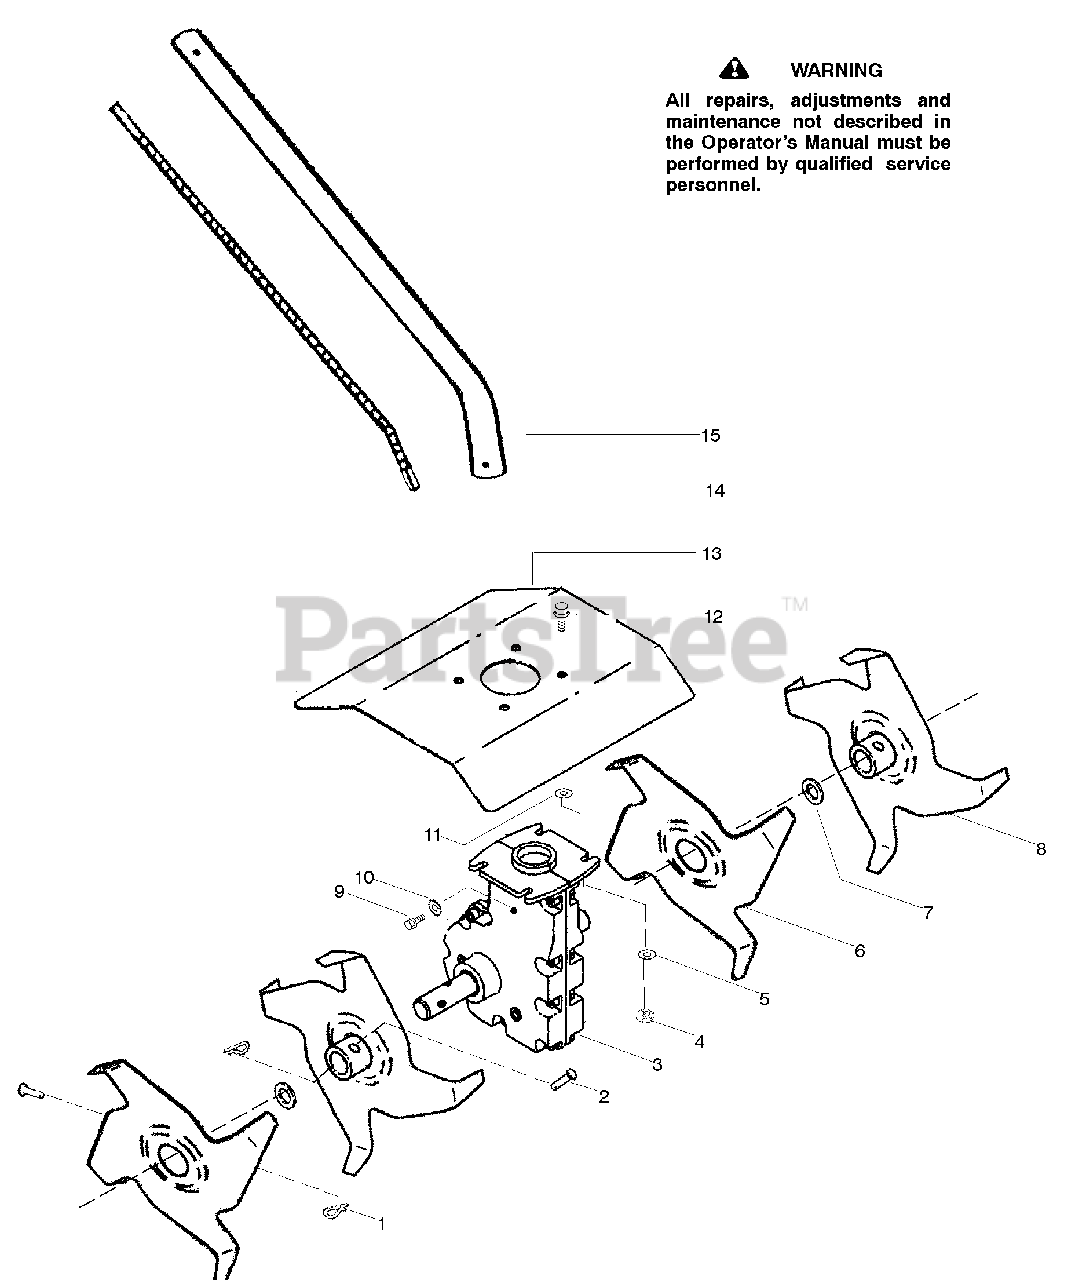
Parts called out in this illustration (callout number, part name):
1	Retainer-Hairpin
6	Tine-Right Outside/Left Inside
8	Tine-Left Outside/Right Inside
12	Bolt-Washer Head
15	Assy-Driveshaft
